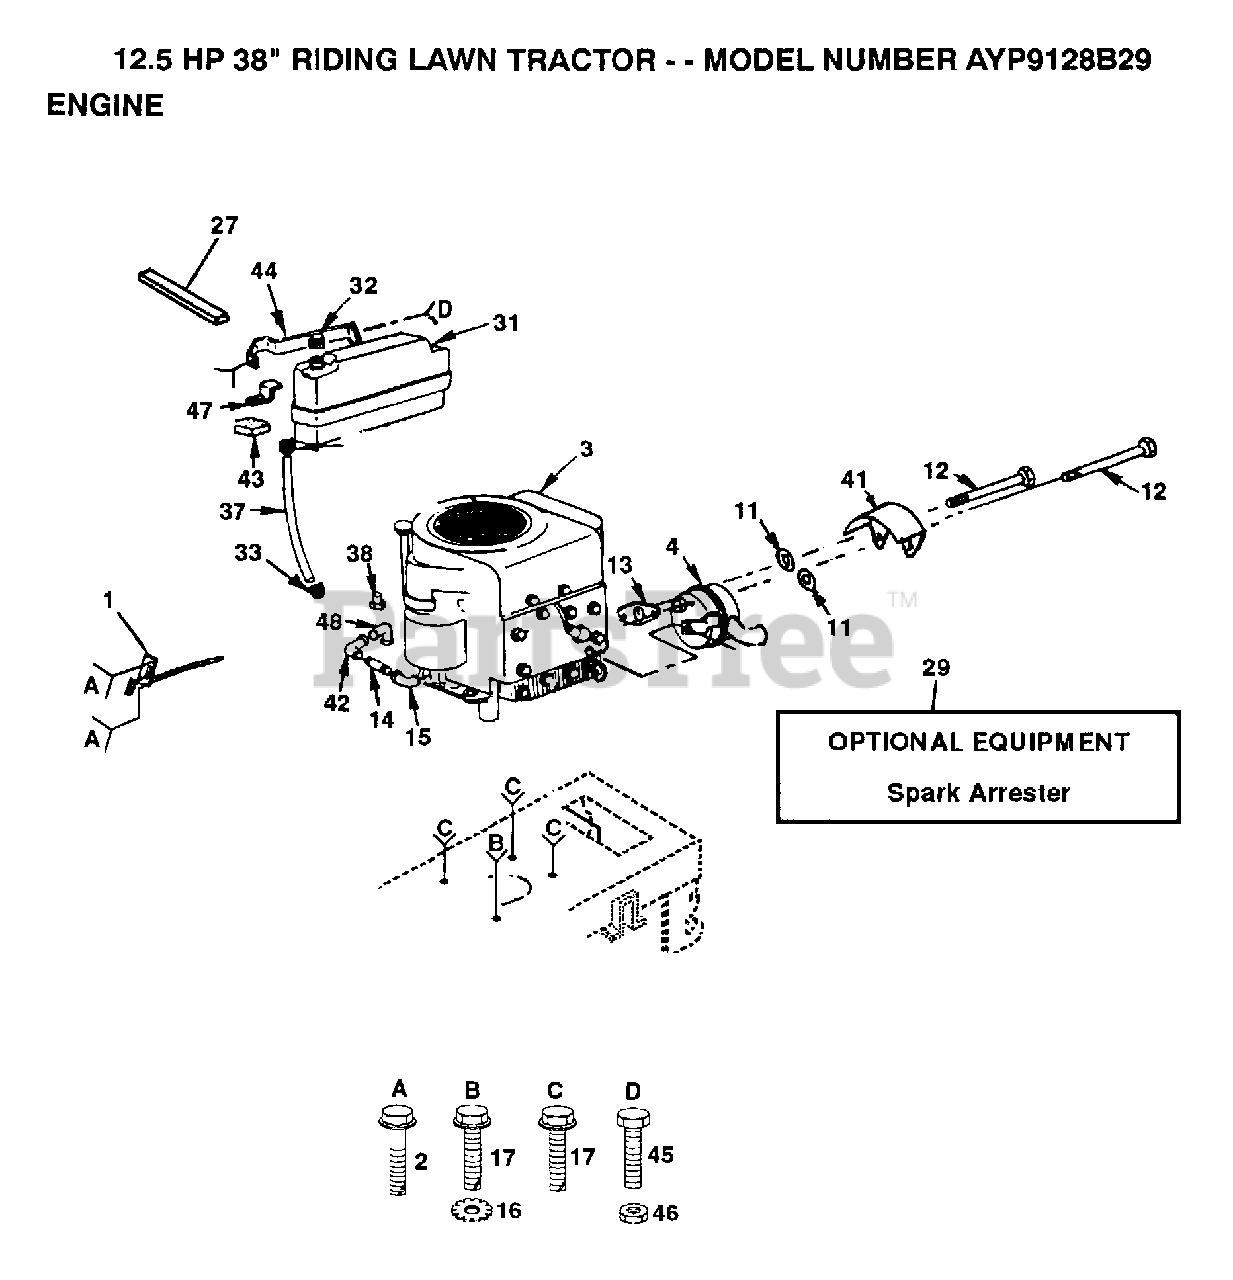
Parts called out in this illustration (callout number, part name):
1	THROTTLE CONTROL
2	SCREW LT
4	MUFFLER
12	BOLT
14	PIPE NIPPLE
15	STREET ELBOW LT
16	LOCKWASHER
17	SCREW
27	FOAM-STRIP LT
31	FUEL TANK
33	HOSE CLAMP
41	HEAT SHIELD
42	STREET ELBOW LT
43	PAD-SPACER T
44	SUPT TANK FUEL
45	BOLT
47	BRACE-TANK LT
48	ELBOW
